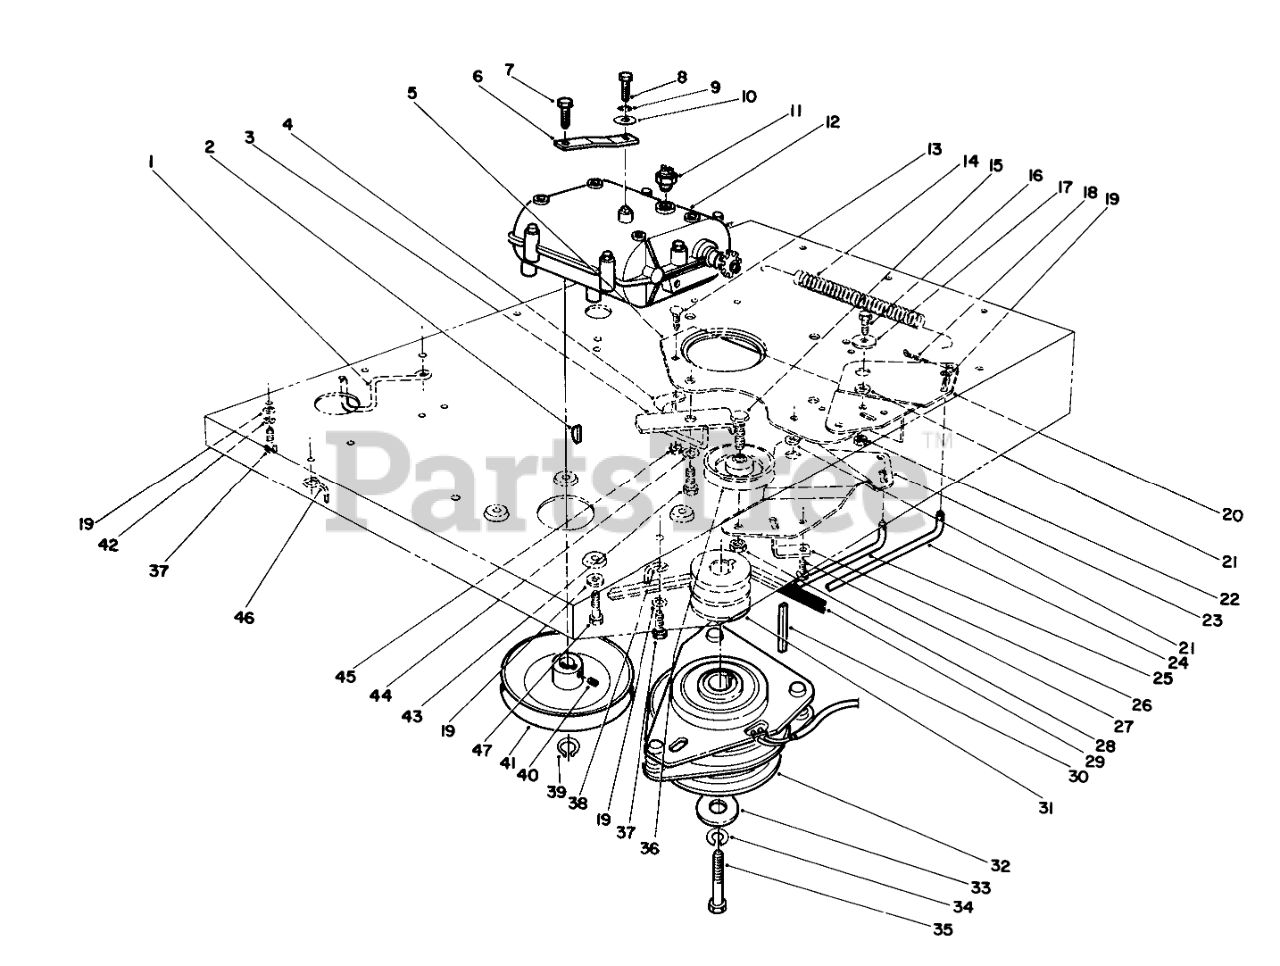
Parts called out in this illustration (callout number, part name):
1	BELT ROD
2	KEY-WOODRUFF
3	CLUTCH RETAINER WA B
4	CLIP-CLOSED, INSULATED
5	PANEL- PIVOT SUPPORT
6	LH SHIFT ARM
7	SCREW-HH
8	SCREW-HH
9	WASHER-LOCK
10	SPACER
11	NEUTRAL SWITCH
12	TRANSMISSION LH
13	SCREW-CARR
14	TRACTION SPRING
15	SCREW-LEVELER
16	SCREW-HH
17	WASHER-PIVOT
18	PIN-COTTER
19	WASHER-PLAIN
20	UPPER PIVOT BRACKET WA
21	SPACER-PIVOT, IDLER
22	NUT-LOCK, NI
23	LOWER PIVOT BRACKET WA
24	LEFT REAR PULL ROD
25	RIGHT REAR PULL ROD
26	BELT RETAINER
27	SCREW-HHFTF
28	NUT-LOCK, NI
29	V-BELT
30	KEY-STOCK
31	TRACTION DRIVE PULLEYB
32	CLUTCH/BRAKE
33	WASHER-CLUTCH
34	WASHER-LOCK
35	SCREW-HH
36	Idler
37	SCREW-HH
38	BELT GUIDE
39	RING-SNAP, EXTERNAL
40	SCREW-SET, HSH
41	PULLEY-TRANSMISSION
42	WASHER-LOCK
43	SCREW-HH
44	WASHER-BELLEVILLE
45	NUT-KEPS
46	BELT GUIDE
47	Screw-HH
